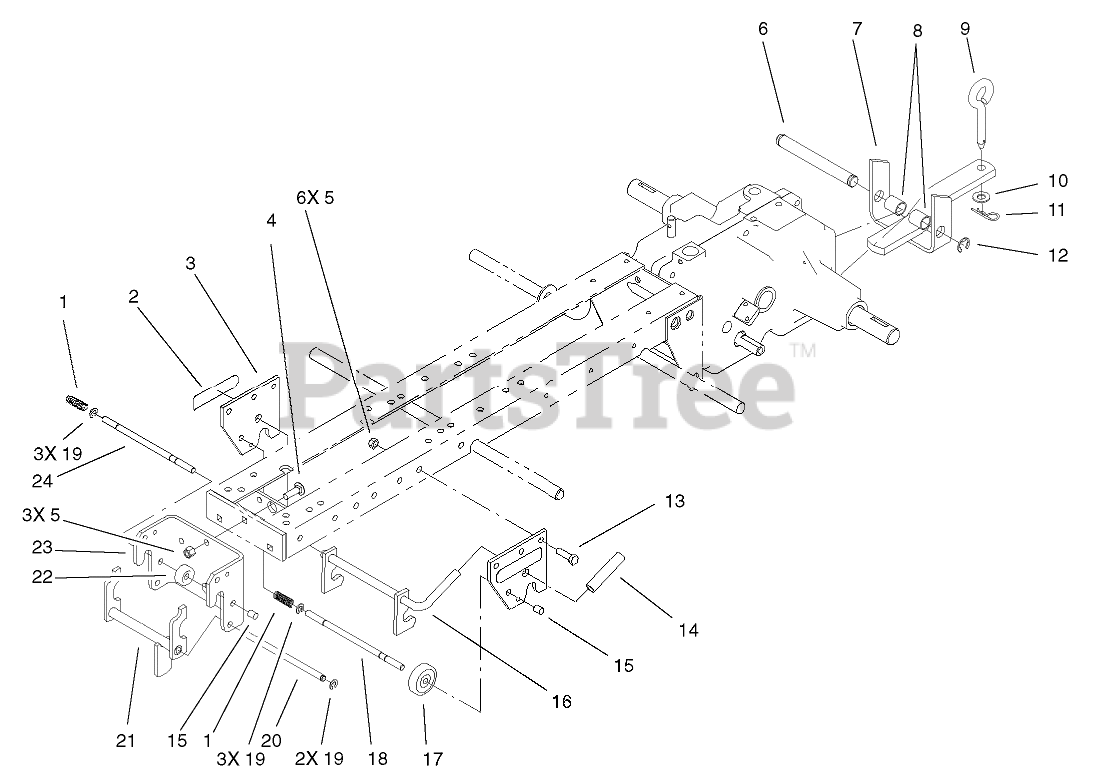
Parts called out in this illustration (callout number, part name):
1	SPRING
2	DECAL-ATTACH A-MATIC
3	PLATE-HITCH
4	BOLT-CARR
5	NUT-LOCK, NI
6	PIN-STATIONARY HITCH
7	HITCH ASM
8	SPACER
9	PIN-TOOL
10	WASHER-FLAT
11	PIN-HAIR
12	E-RING
13	SCREW-HH
14	GRIP
15	CAP-ROD, PLUNGER
16	MID HITCH ASM
18	ROD-LOCK
19	RING-RETAINING
20	ROD-LATCH PIVOT
21	LATCH
23	HITCH-FRONT
24	ROD-LOCK
